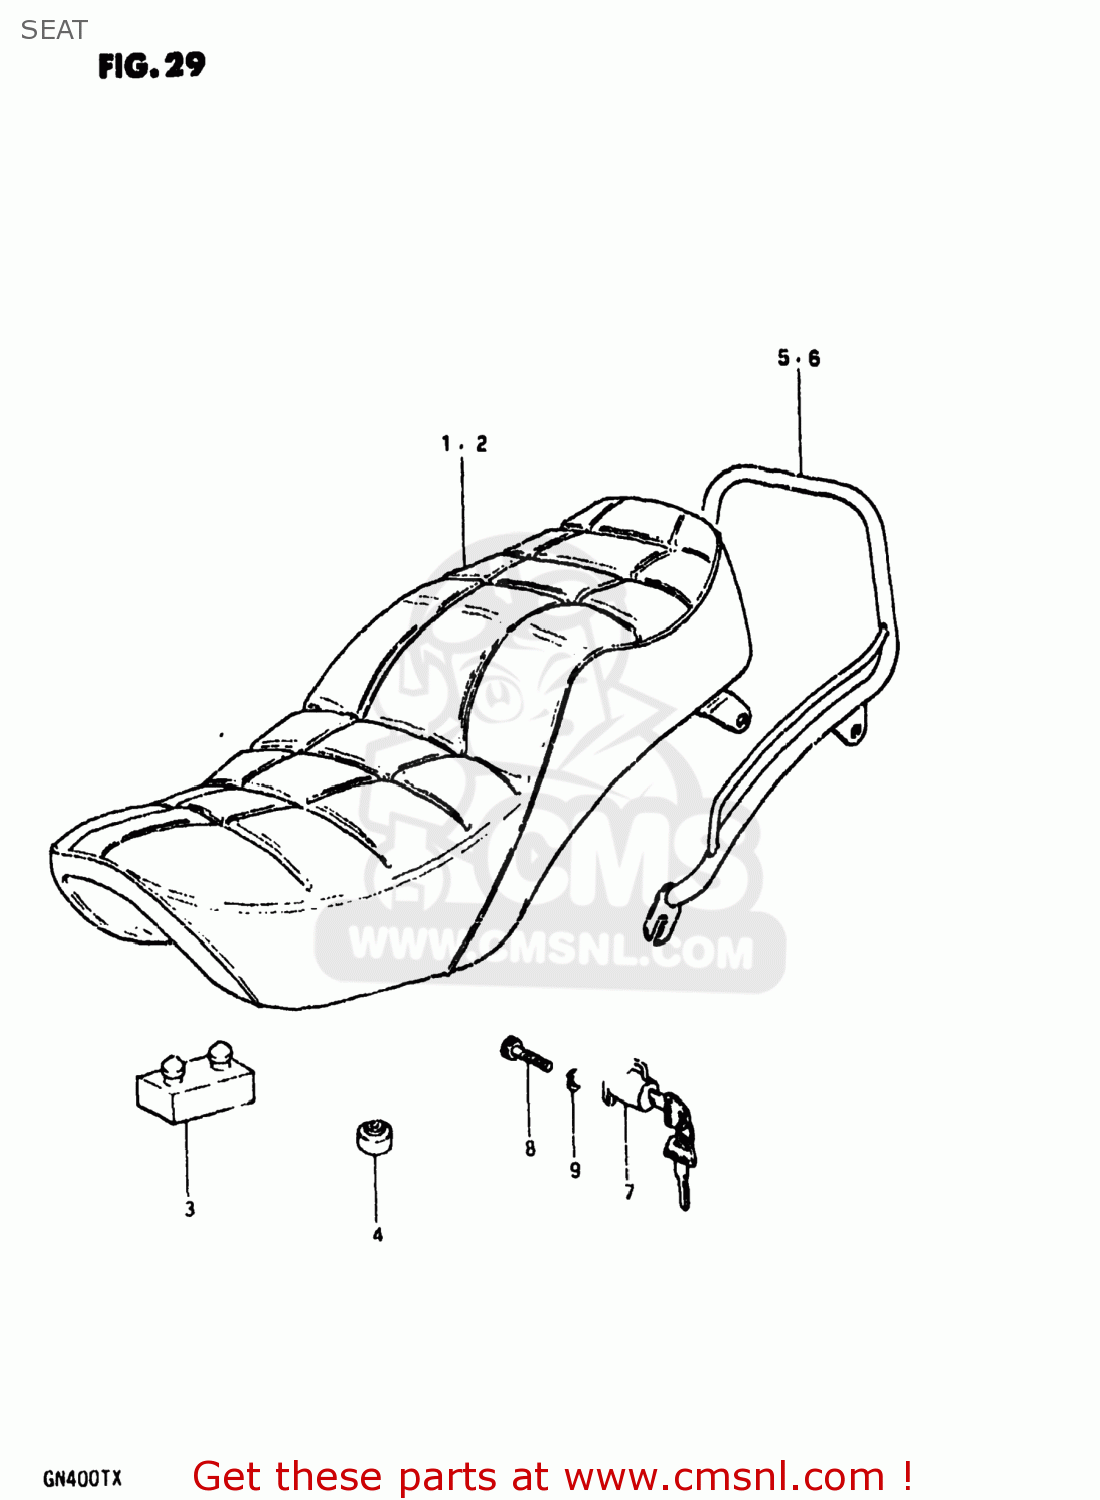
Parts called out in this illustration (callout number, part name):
1	SEAT ASSEMBLY
2	SEAT ASSEMBLY
3	CUSHION
4	CUSHION
5	HANDLE,PILLION RIDER
6	HANDLE,PILLION RIDER
7	LOCK ASSEMBLY,HELMET
8	BOLT 6X11
9	LOCK WASHER
